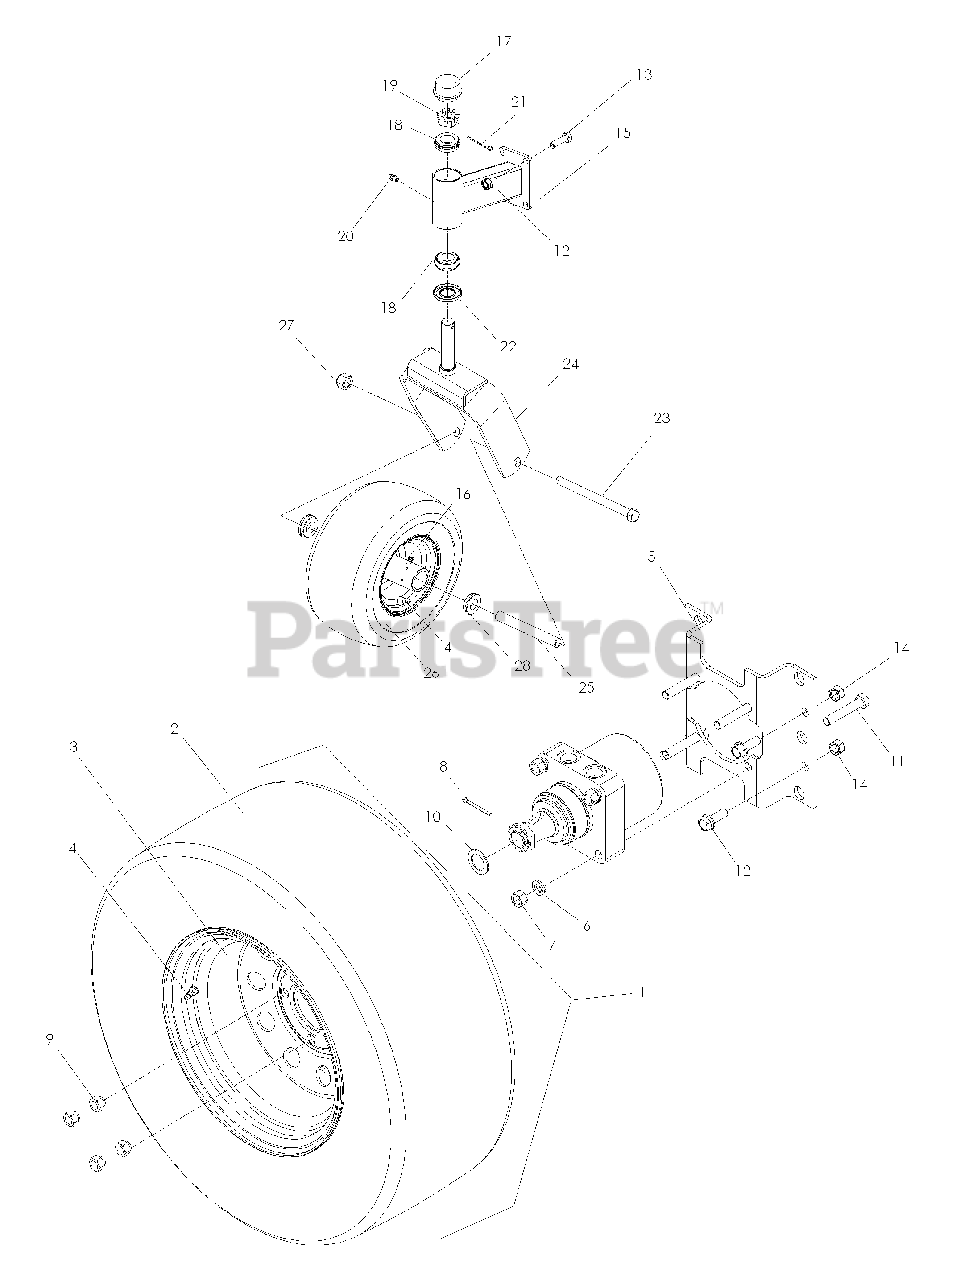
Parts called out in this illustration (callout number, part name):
1	TIRE ASSEM, RR 23 x 9.5-12
3	RIM RR
5	MOUNT WHEEL MOTOR
6	WASHER, 1/2 SPLT LOCK
7	NUT 1/2-13 HEX
8	COTTER PIN
9	LUG NUT 1/2
10	BUSHING, 1 x 14 GA
11	HCS 1/2-13 x 2 3/4
12	NUT 7/16-14
13	HCS 7/16-14 x 1
14	NUT 1/2-13 HEX NYLOC
15	CASTER ARM
17	CAP GREASE
18	BEARING-ROLLER
19	NUT 1-14 SLOTTED JAM
21	COTTER PIN
23	HCS 1/2-13 x 7 1/2
24	YOKE, CASTER
25	SPACER, AXLE
26	WHEEL ASSEM, CASTER
27	NUT 1/2-13 HEX NYLOC
28	FLANGE BEARING
